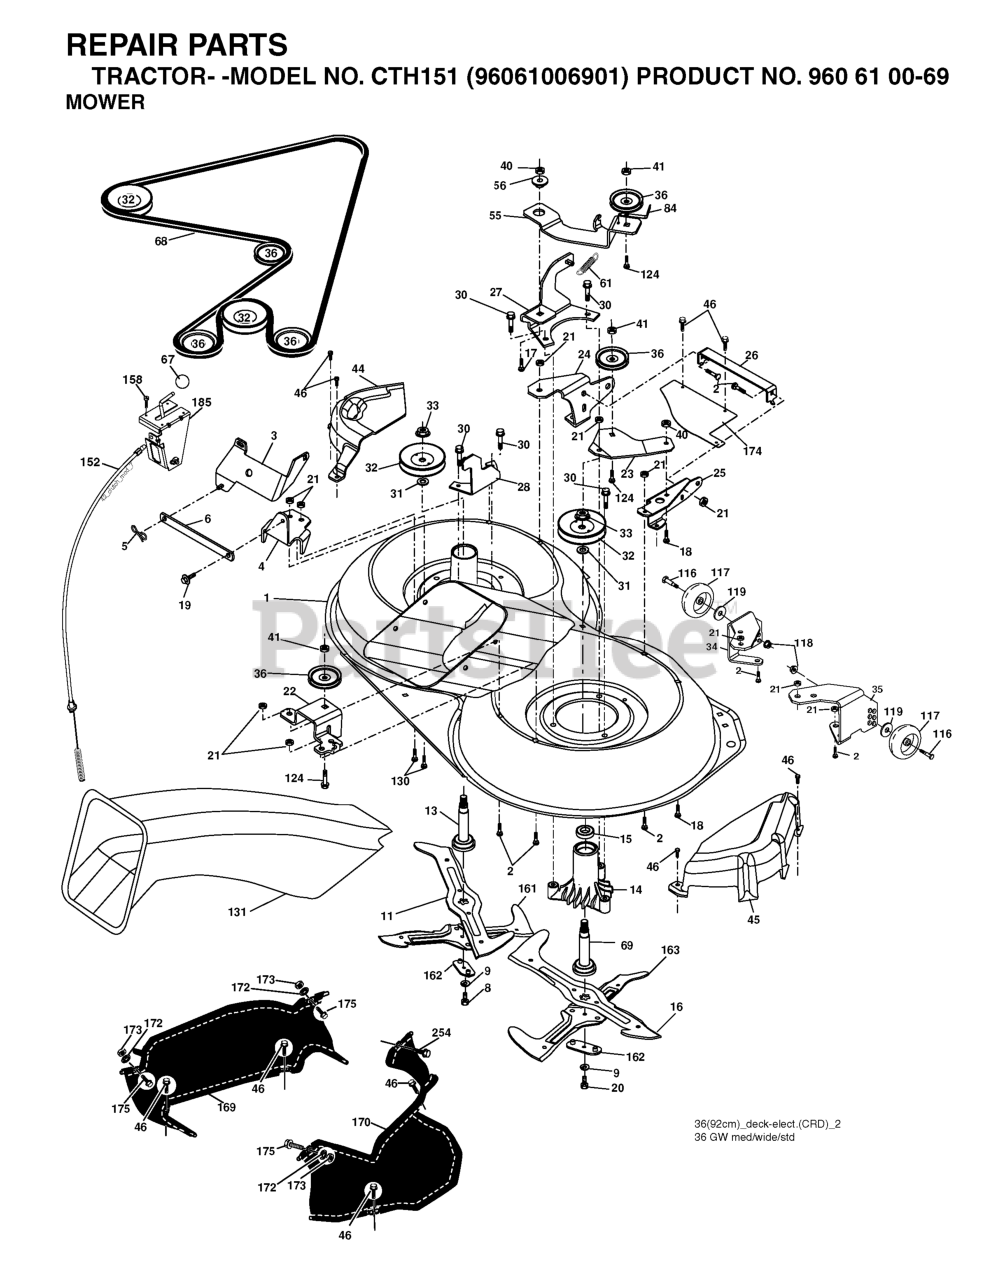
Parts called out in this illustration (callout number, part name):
2	RP BOLT 5/16-18 X3/4 ZN/YEL GR
5	RETAINER-SPRNG RB
6	BAR.SWAY.92.CRD
8	BOLT.3/8-24X1.25 GR8
9	LOCKWASHER
13	SHAFT ASM VENT
14	HOUSING.MANDREL.VENTED (MACHD)
17	BOLT.3/8-14X1.25
18	BOLT
19	BOLT SHD 5/16-18
20	BOLT.3/8-24X1.25GR8. LHTHRD
21	LOCKNUT
26	SUPPORT
30	SCREW, WASHER HEAD
31	WASHER.SPACER.MANDREL
33	NUT.FLANGE.LOCK.TOP
36	PULLEY.IDLER.4.25
41	NUT LOCK FLG 3/8-16 UNC
45	COVER.MANDREL.RH.CRD
46	SCREW.1/4-20X5/8
55	ARM.IDLER.92 CRD.2006
56	SPACER.RETAINER.MOWER
61	SPRING.TENSION.BELT
67	KNOB T (3/8 HOLE)
68	BELT.DRIVE.92CM.CRD.2006
69	SHAFT.ASM.W/LWR.BRG.RH.THREAD
84	KEEPER, BELT IDLER
116	SHOULDER BOLT
117	RP WHEEL. GUAGE RALLY
118	LOCKNUT
119	WASHER.5/16.FLAT.STE.STD.
124	BOLT.3/8-16X1.50
130	BOLT.CARR.SQNK.5/16-18UNC.X3/4
131	CHUTE BAGGER
158	SCREW
169	COVER TERMINAL BATTERY
172	PUSH.NUT.ROUND.3/8.DIAM
173	NUT
175	BOLT D
185	HEAD ASM. CABLE CLUTCH
254	SCREW 3/8-16X1
